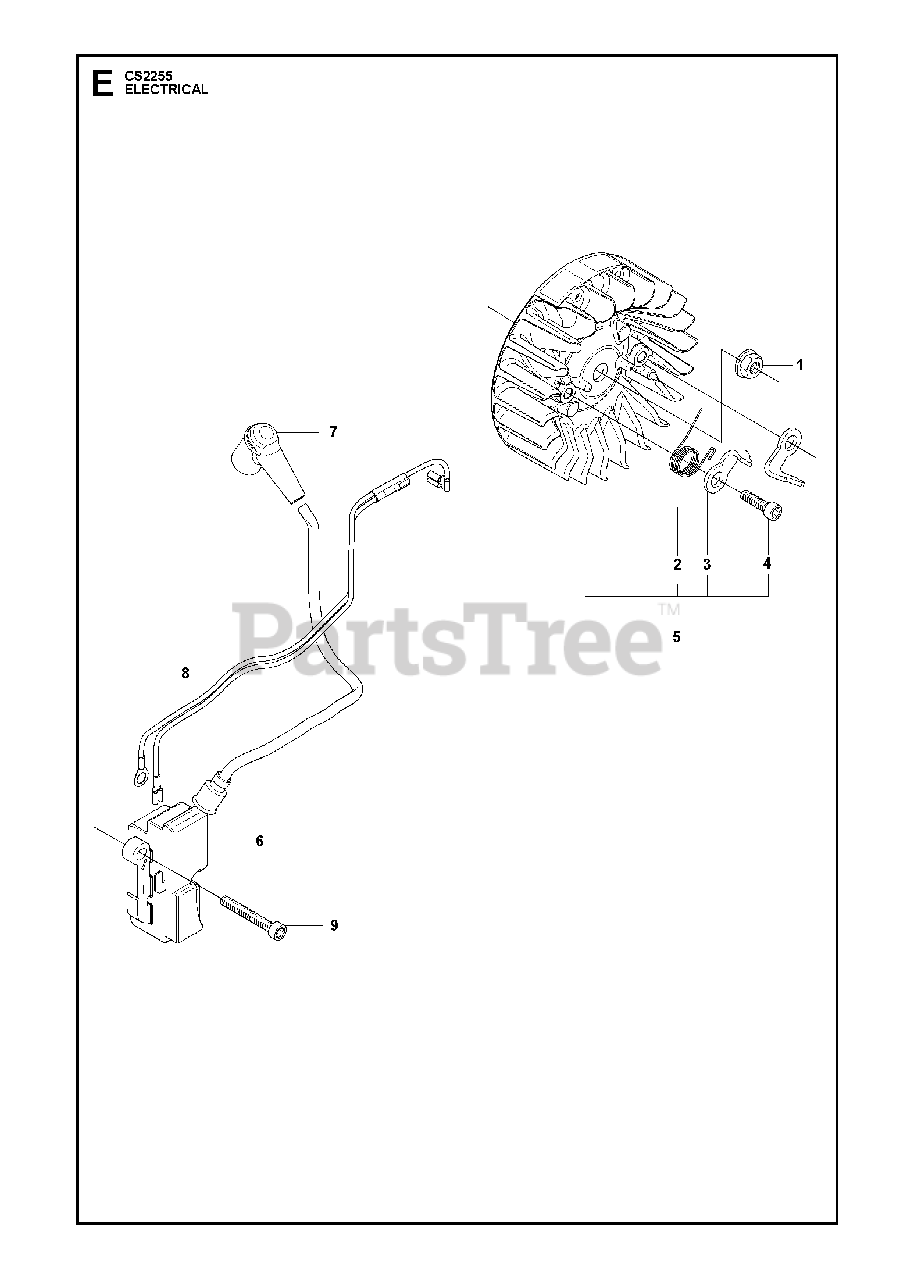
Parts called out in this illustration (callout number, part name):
1	NUT W/ WASHER
2	%SPRING, STARTER CATCH
3	PAWL
4	PIN, STARTER CATCH
6	IGNITION MODULE
7	SPARK PLUG CONN. KIT
8	CABLE ASSY
